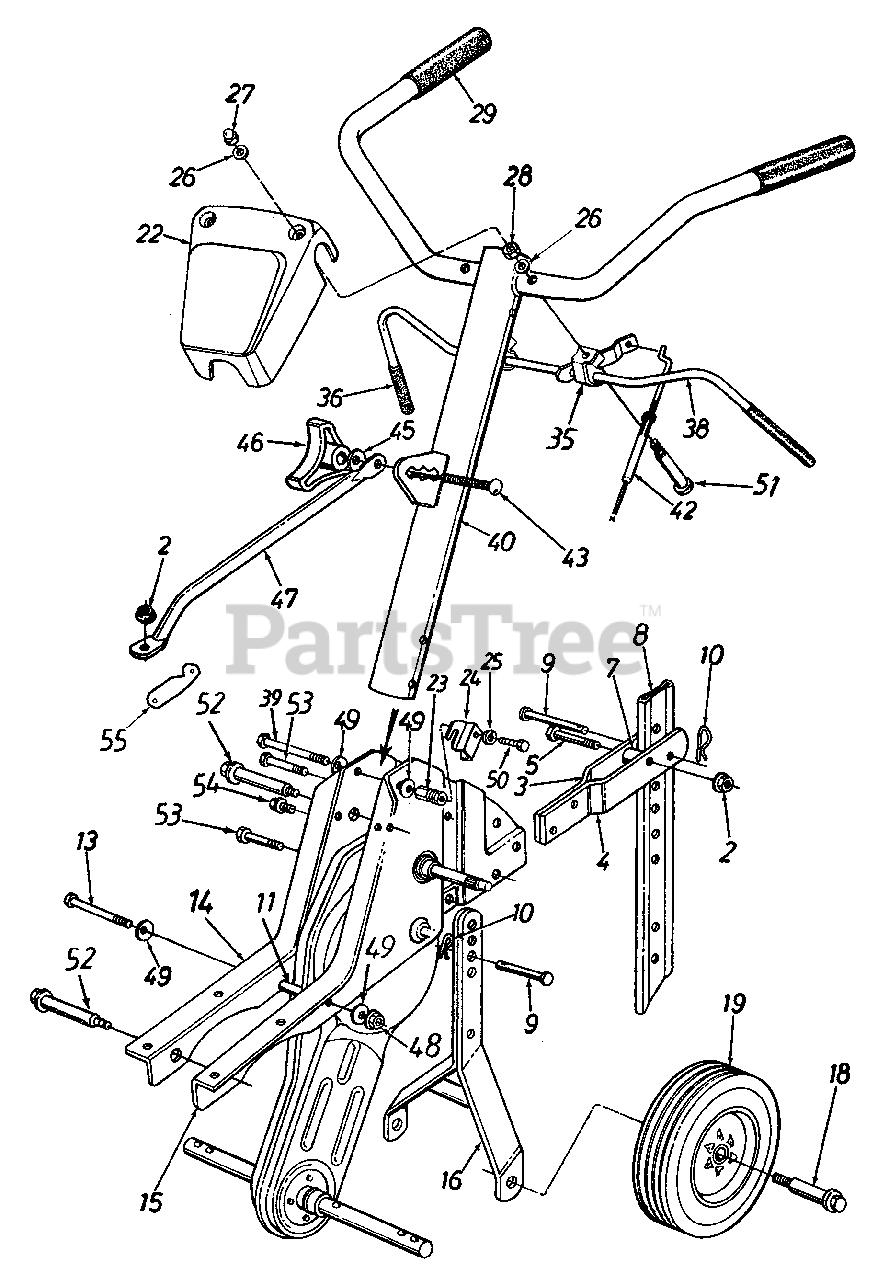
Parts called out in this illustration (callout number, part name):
2	Hex Flange L-Nut 5/16-18 Thd. (Gr. 5)
5	Hex Bolt 5/16-18 x 1.5" Lg.
7	Spacer .32" I.D. x .75" O.D.
9	Clevis Pin .375" I.D. x 1.62" Lg.
10	Internal Cotter Pin
11	Spacer .326" I.D. x .47" O.D.
13	Hex Bolt 5/16-18 x 2.75" Lg.
18	Shld. Bolt .496" Dia. x 1.45"
19	Wheel Ass'y.
22	Handle Cover
23	Spec. Hex Nut
25	L-Wash. 5/16" I.D.
26	Fl-Wash. .266" I.D. x .625" O.D.
27	Hex L-Stop Nut 1/4-20 Thd.
28	Hex Nut 1/4-20 Thd.
29	Grip-Handle
35	Clutch Handle Holder
36	Grip-Clutch
39	Hex Bolt 5/16-18 x 3" Lg.
43	Carr. Bolt 5/16-18 x 1" Lg. (Special)
45	Wash. Bell. .340" ID x .872" OD
46	Hand Knob
49	Bell-Wash. .345" I.D. x .88" O.D.
50	Hex Bolt 5/16-18 x.75" Lg
51	Hex Bolt 1/4-20 x 2.25" Lg.
52	Shld. Bolt
53	Hex Wash. Hd. TT-Tap Scr. 5/16-18 x .62" Lg.
54	Hex Wash. Hd. TT-Tap Scr. 5/16-18 x 1" Lg.
55	Engine Brkt.
